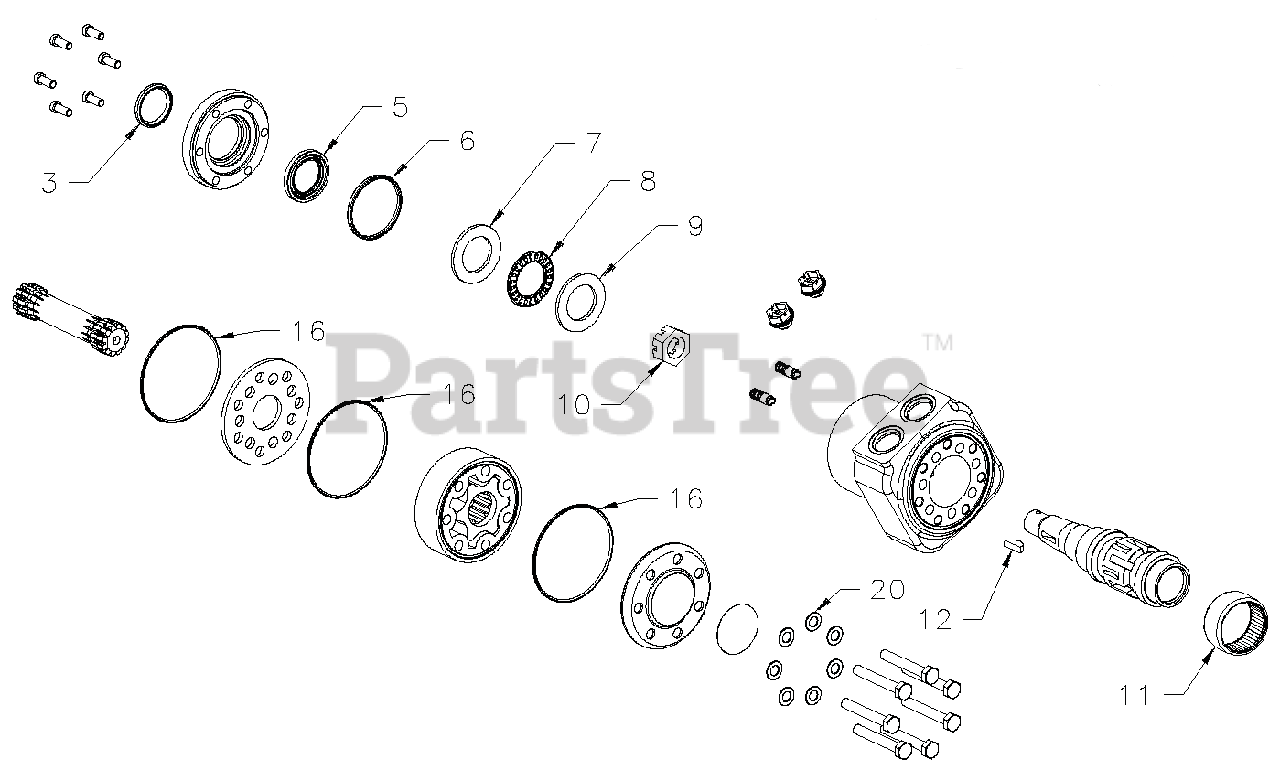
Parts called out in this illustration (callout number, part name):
10	Nut, Castle .75-20 Slotted Hex
NS	SEAL KIT HGM HYDROGEAR 70626-1
NS	SEAL KIT HGM HYDROGEAR 70626-2
NS	BEARING KIT HYDROGEAR 71501
